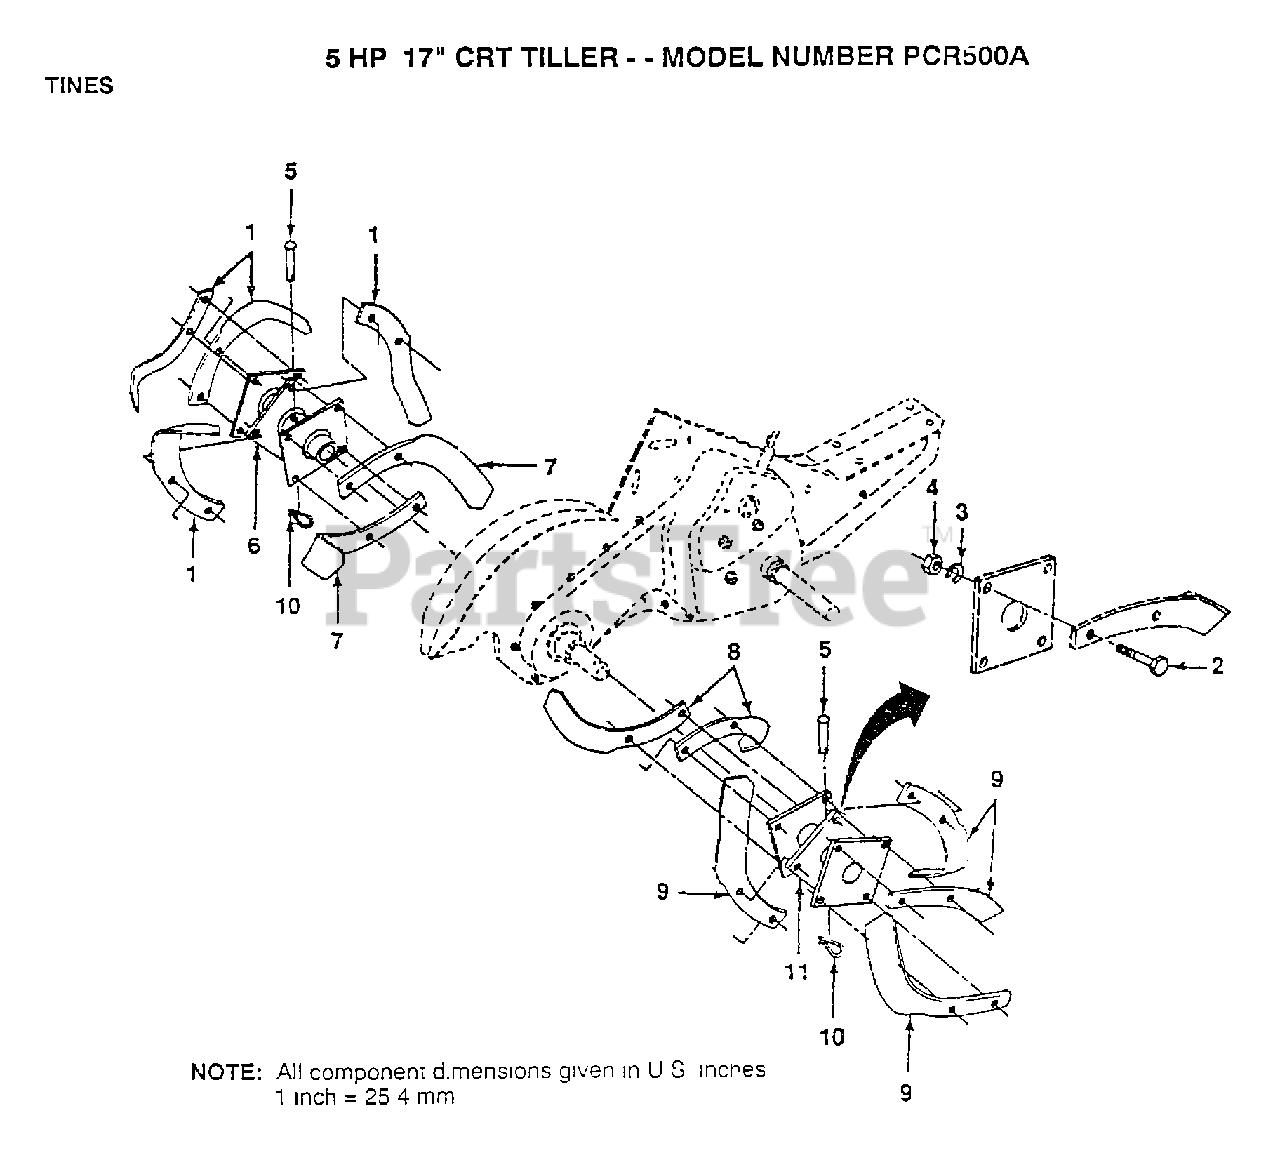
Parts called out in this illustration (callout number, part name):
2	BOLT
3	LOCKWASHER
5	RIVET.PAN HD.1.75
6	TINE ASSY LH CRT
7	"TINE.LH.12"""
8	"TINE.RH.12"""
10	RETAINER.SPRING
11	TINE ASSY RH CRT
